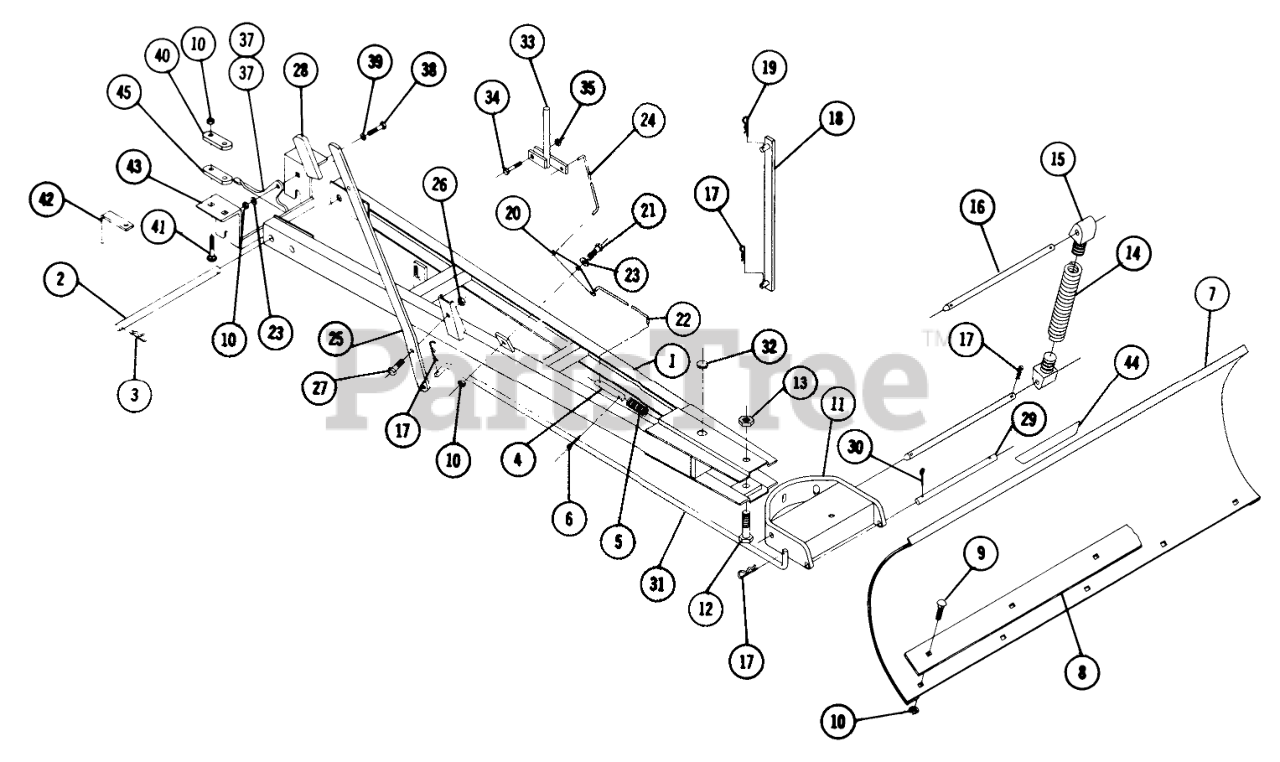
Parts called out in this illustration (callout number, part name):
1	Ass-y. Frame
2	Mounting Shaft
3	Hairpen
4	Index Pin
5	SPRING-COMPRESSION
6	Cotter Pin 1/8
7	Blade
8	Plate
9	Bolt-3/8-16 x 3/4
10	3/8-16 E.S.
11	Sector and Channel
12	Bolt Hex 3/4-16 x 3 3/4
13	Nut-3/4-16 E.S.
14	Spring
15	Lug
16	ROD-PIVOT, BLADE
17	Hairpin
18	LIFT BAR ASSY R
19	Hairpin-Upper
20	Index Plate
21	Bolt 3/8-16 x 1
22	Head-Cylinder
23	Washer
24	Pulley Idler
25	Lever Index
26	Nut-1/2-13
27	Bolt Hex 1/2-13 x 1
28	GRIP
29	ROD-LOWER
30	Cotter Pin
31	Rod Blade Control
32	PLUG
33	INDEX LEVER
34	Bolt-Hex 1/4-20
35	Nut-Nylok
36	Latch Hitch
37	Plate Latching L.H.
38	Bolt 3/8-16 x 1
39	Lockwasher
40	Link
41	Bolt Carriage 3/8-16 x 3 3/4
42	SPACER-BRACKET
43	Hitch Axle Mounting
44	Decal
45	Spacer
